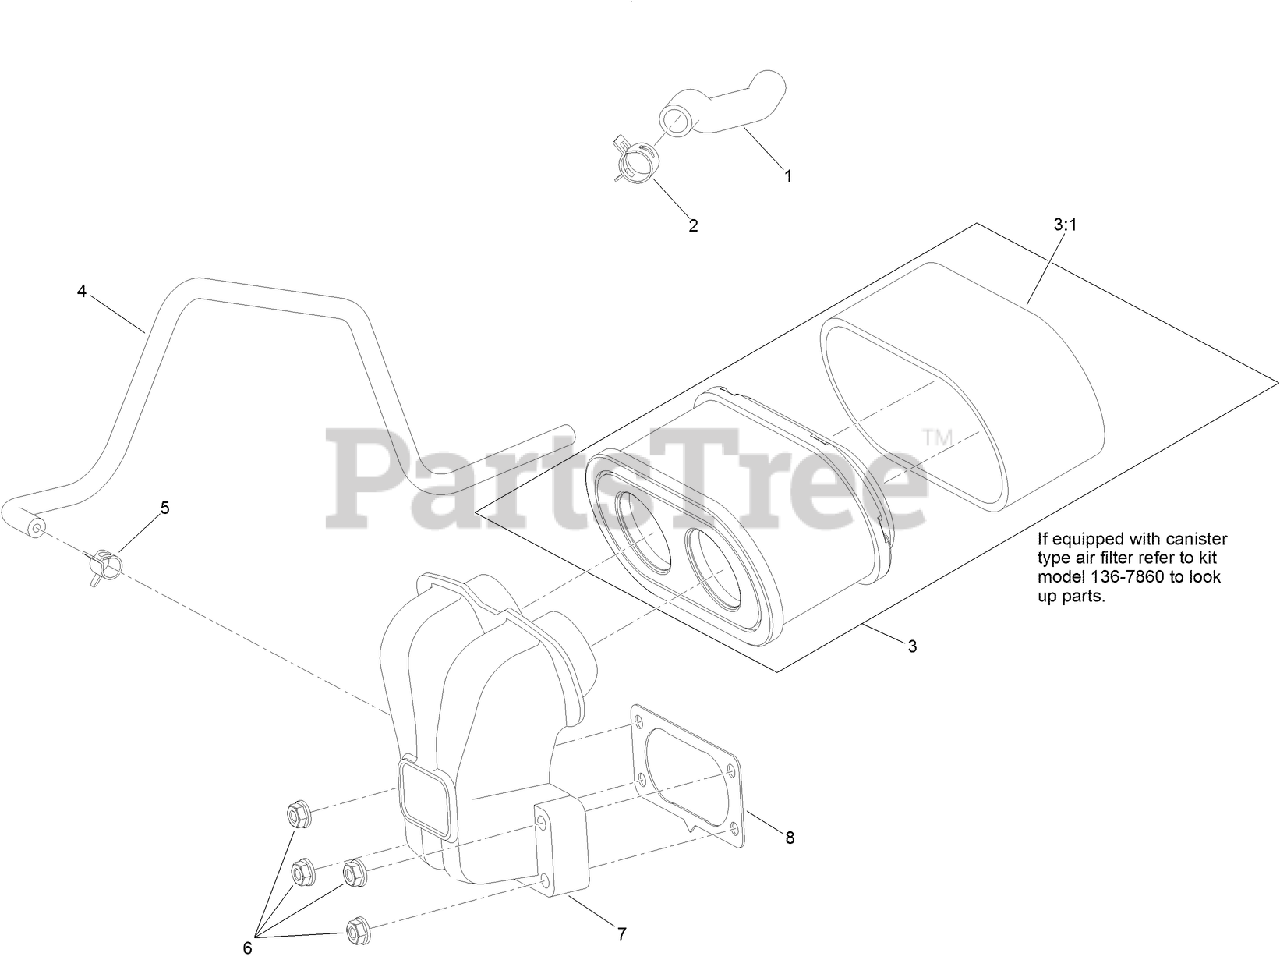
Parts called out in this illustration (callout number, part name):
1	TUBE-BREATHER
2	CLAMP-HOSE
3	FILTER-AIR, COMPLETE
3:1	FILTER-PRE, FOAM
4	HOSE-FUEL
5	CLAMP-HOSE
6	NUT-FLANGE
7	MANIFOLD-FILTER, AIR
8	GASKET-CARBURETOR
